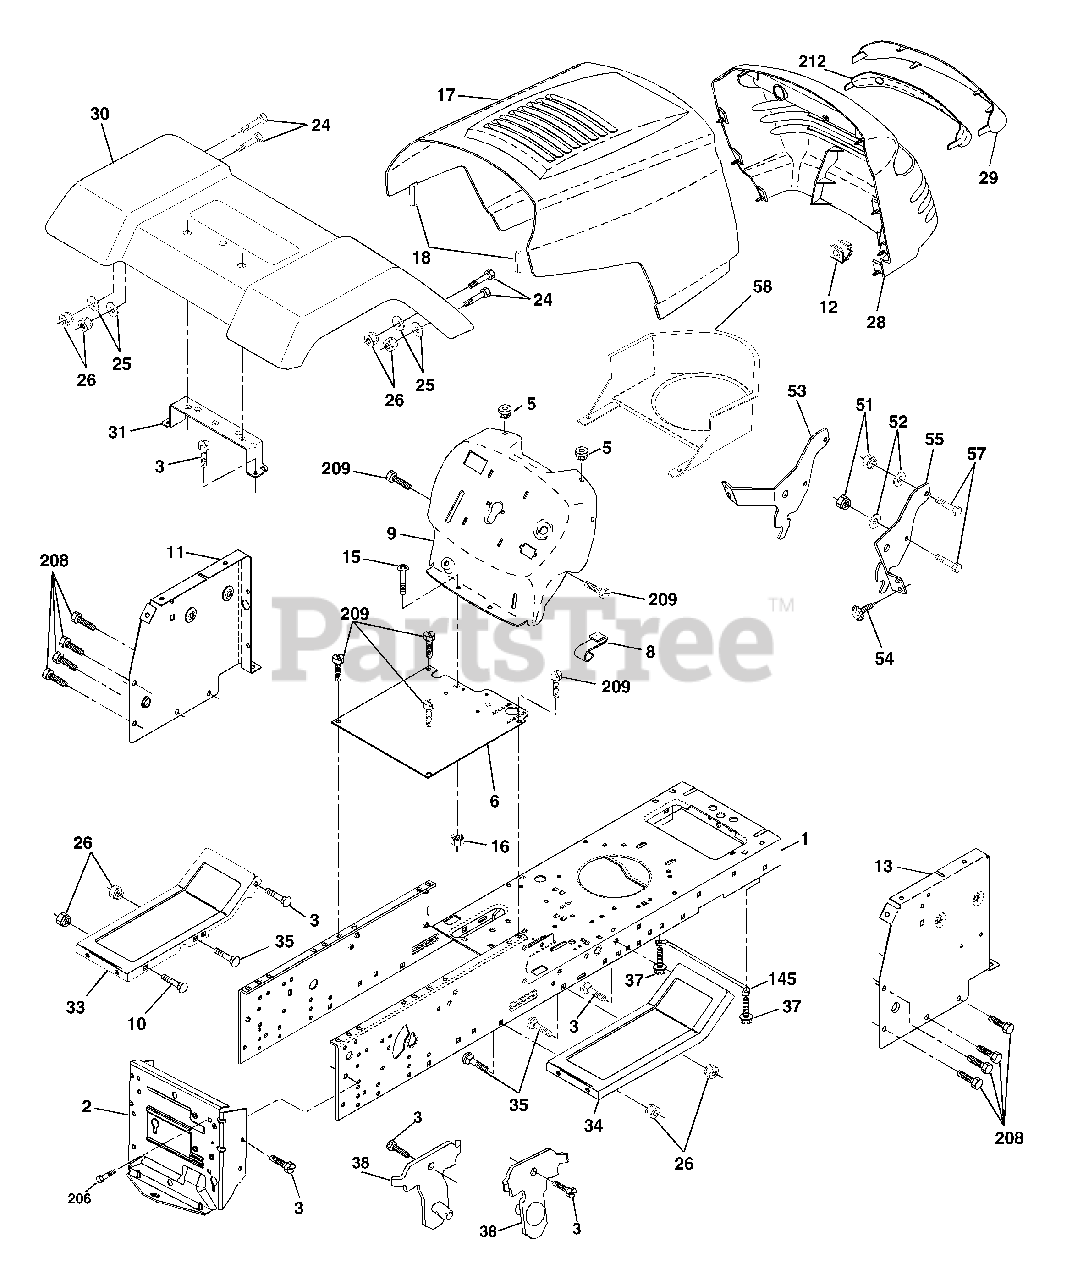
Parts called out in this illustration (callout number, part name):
2	Drawbar, Stretch
3	Screw 3/8-16 x 3/4
5	Bumper,Hood/Dash
6	Saddle Silkscreen Flt Sdl
8	Clip Retainer Slide-On
9	Dash
10	Bolt, Carriage 3/8-16 x 1
11	Panel Dash LH
12	Clip Tinnerman Grille P.L
13	Panel Slkscr Dash RH
15	Screw Mach TRHD 5/16-18uncx3/4
16	Nut Keps 5/16-18 Unc
17	Hood
18	Bumper Hood
24	Bolt Fin Hex 3/8-16unc X 1 Gr. 5
25	Washer 13/32 X 13/16 X 12 Ga
26	Nut Lock Hex w/Ins 3/8-16 Unc
28	Grille P.L Ms 428
29	Lens Grille Private Label
30	Fender
31	Bracket Fender Repl 109873x
33	Footrest Pnt LH Perf
34	Footrest Pnt RH Perf
35	Bolt Rdhd Sht Sqnk 3/8-16 X3/4
37	Screw Thdrol 5/16-18 x 1/2 TYT
38	Bracket Asm. Pivot Mower Rear
51	Nut Lock W/Insert 1/4-20unc
52	Washer 9/32 x 7/8x16 Ga.
53	Bracket Grille Lh
54	Screw Hex 8-18 x 7/8
55	Bracket Grille Rh
57	Bolt Fin Hex 1/4-20 unc x .75
58	Duct Air Engine PL/LT
145	Rod Pivot Chassis/Hood
206	Bolt Shoulder 5/16-18
208	Screw Thdrol 3/8-16 x 1/2
209	Screw Hex Wsh Thdrol 3/8-16
212	Insert Lens Reflect
